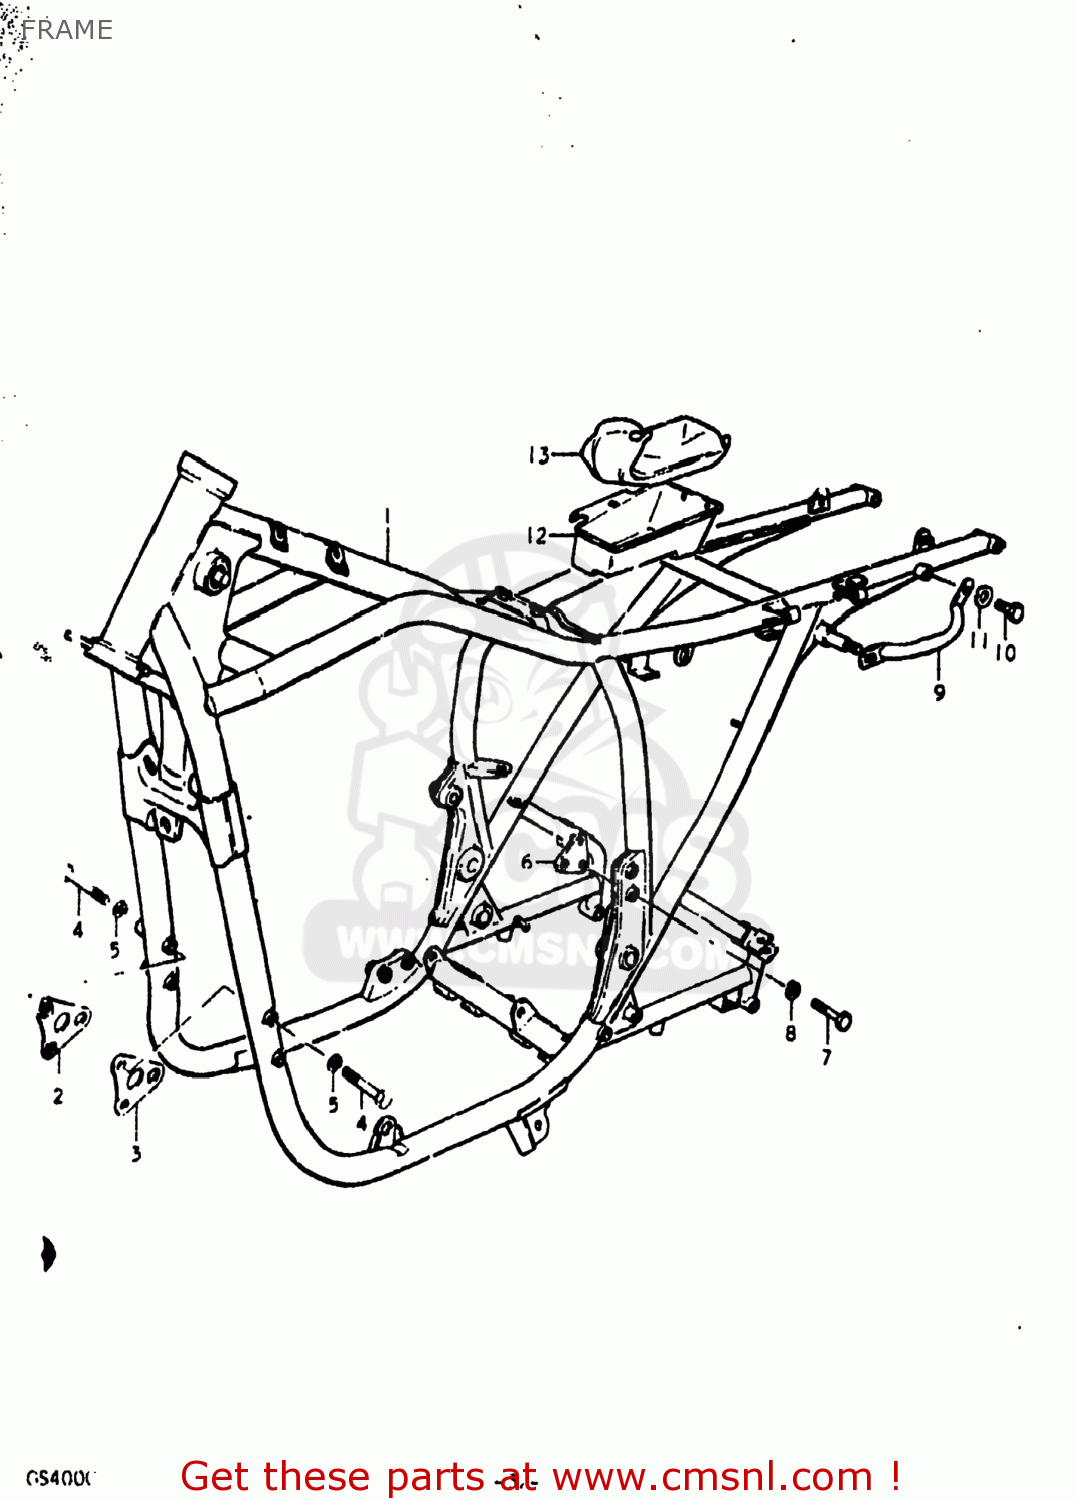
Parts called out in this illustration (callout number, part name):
1	FRAME
2	PLATE,ENGINE MOUNTING
3	PLATE,ENGINE MOUNTING
4	BOLT
5	LOCK WASHER
6	PLATE,ENGINE MOUNTING
7	BOLT 8X40
8	LOCK WASHER
9	GRIP,FRAME HANDLE
10	BOLT
11	WASHER
12	HOLDER,TOOL
13	TOOL SET
